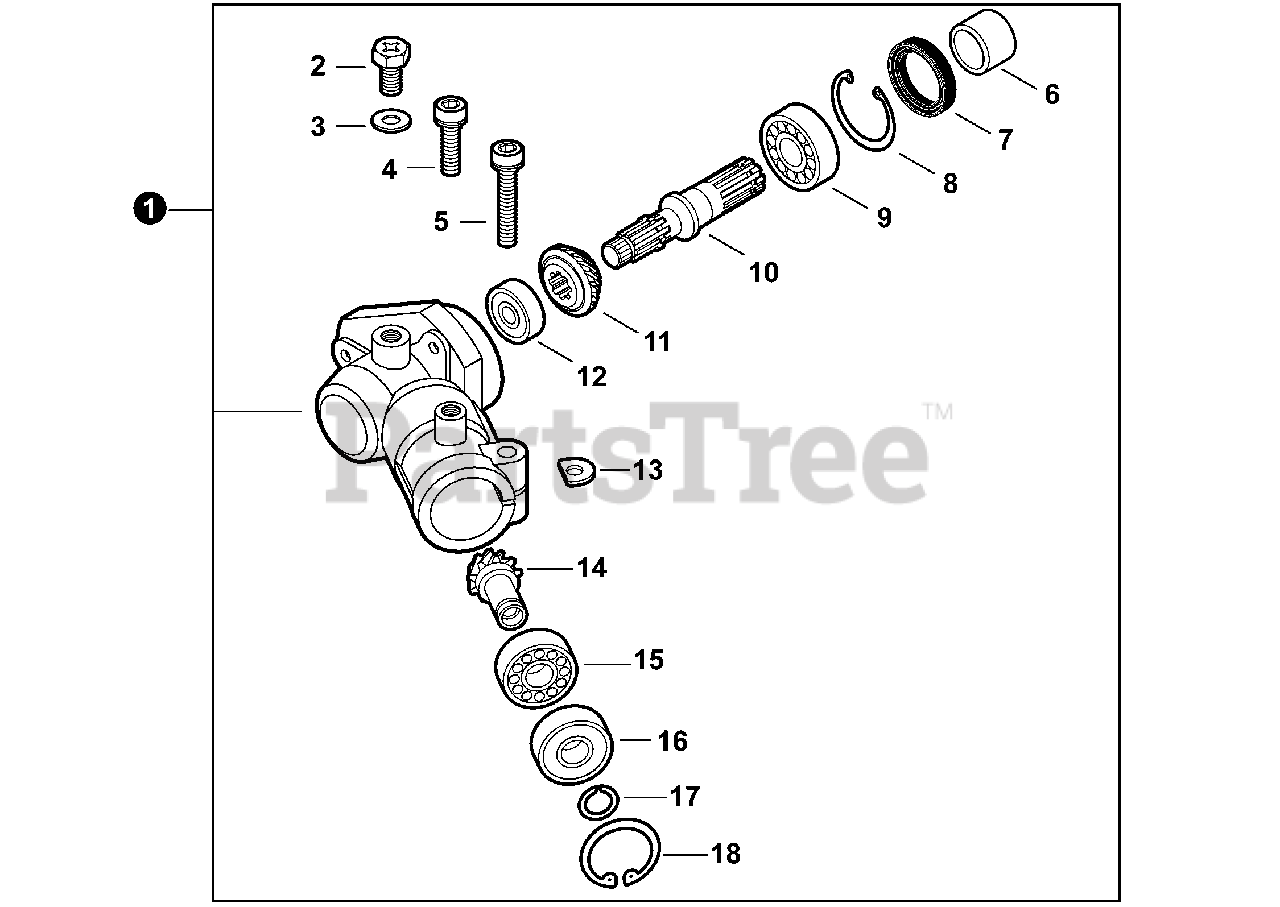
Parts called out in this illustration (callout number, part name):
1	GEAR CASE ASSY
2	BOLT M6×10
3	WASHER 6.5×11.5×0.8
4	BOLT M5×16
5	BOLT M5×25
7	SEAL, OIL
8	RING, SNAP Ø28
9	BEARING, BALL 6001
10	SHAFT, GEAR
11	GEAR, BEVEL
12	BEARING, BALL 608 DDU
13	D-WASHER
14	PINION, BEVEL
15	BEARING, BALL 609
16	BEARING, BALL 609ZZ
17	RING, SNAP Ø9
18	RING, SNAP Ø24
